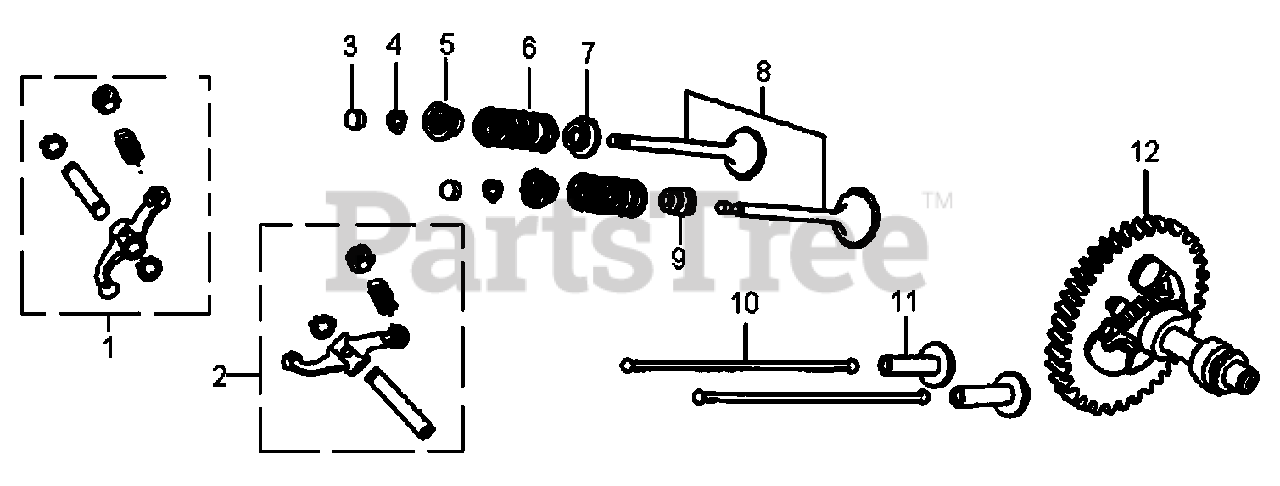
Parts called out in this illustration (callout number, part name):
1	ARM ASSY., ROCKER
2	ARM ASSY., ROCKER
3	VALVE, ROTATOR
4	VALVE, KEEPER
5	RETAINER,VALVE SPRING
6	SPRING, VALVE
7	SEAT, VALVE SPRING
8	VALVE ASSY.
9	SEAL, VALVE STEM
11	LIFTER, VALVE(TAPPET)
12	CAMSHAFT ASSY
